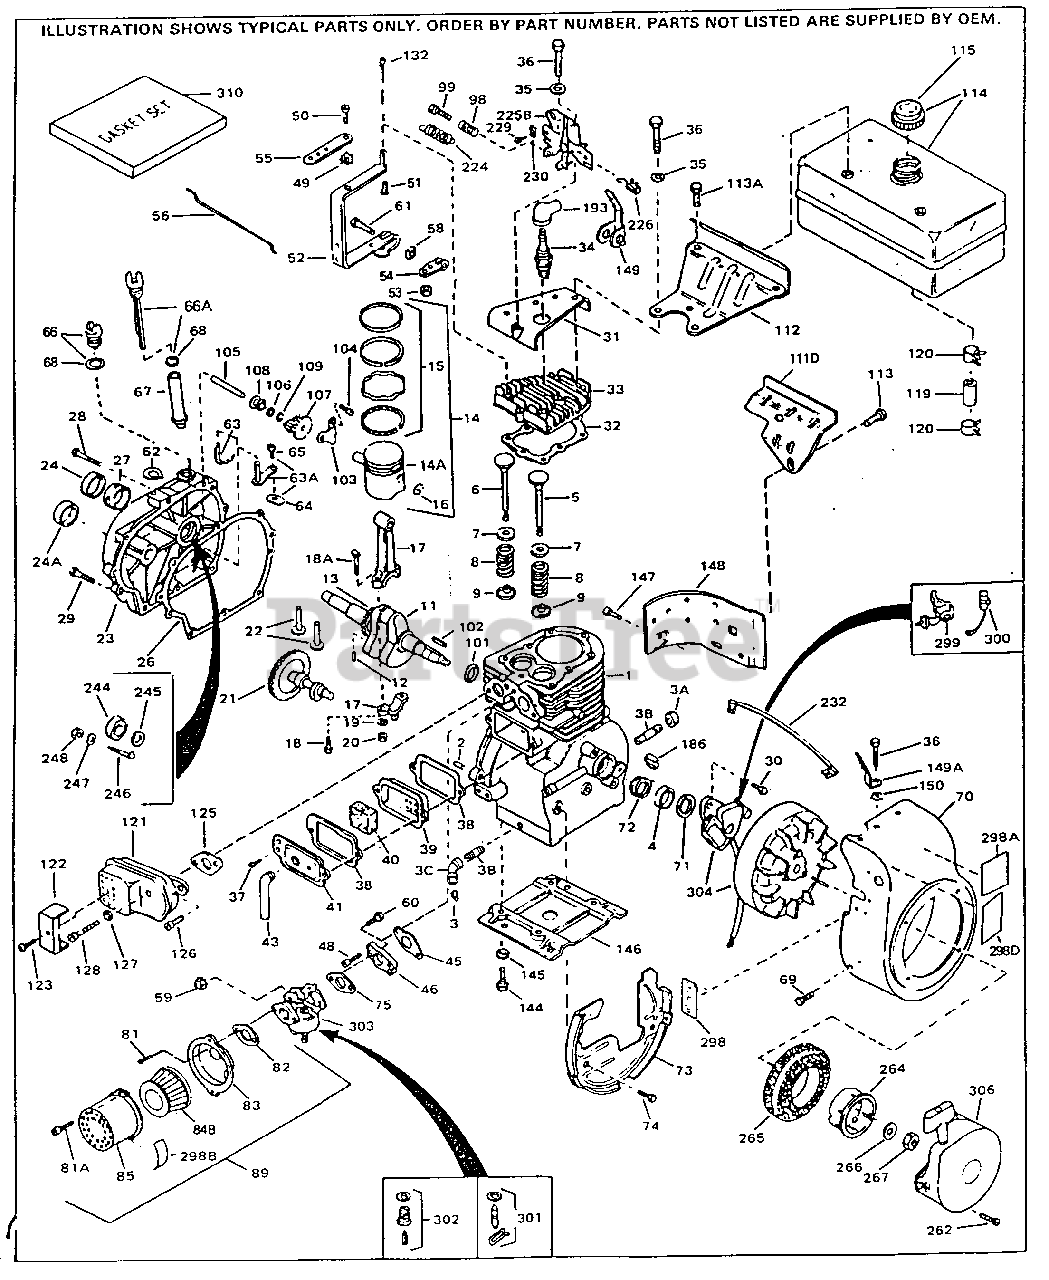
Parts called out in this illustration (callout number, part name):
1	"Cylinder (Incl. 2,3,4,5,184) 2-5/8" B ore
2	Dowel Pin
3	Oil Drain Plug (Sq. hd., 1/4-18)
4	Seal, Oil
5	Intake Valve (Std.) (Incl. 9)
5	Intake Valve (1/32" OS) (Incl. 9)
6	Exhaust Valve (Std.)(Incl. 151)
6	Exhaust Valve (1/32" OS) (Incl. 151)
7	Valve Spring Cap
8	Valve Spring
9	Cap, Lower valve spring
11	Crankshaft (Incl. 12 & 13)
12	Pin, Crankshaft gear Used in early pr oduction. This gear is serviceable O NLY when itis pinned to the crankshaf t.
13	Gear, Crankshaft Used in early produc tion. This gear is serviceable ONLY when itis pinned to the crankshaft.
14	Piston, Pin & Ring Set (Std.) 2-5/8" Bore
14	Piston, Pin & Ring Set (.010" OS)
14	Piston, Pin & Ring Set (.020" OS)
14A	Piston & Pin Ass'y. (Std.)(2-5/8") In cl. 16
14A	Piston & Pin Ass'y. (.010" OS) Incl. 16
14A	Piston & Pin Ass'y. (.020" OS) Incl. 16
15	Ring Set (Std.) (2-5/8" Bore)
15	Ring Set (.010" OS)
15	Ring Set (.020" OS)
16	Piston Pin Retaining Ring
17	Rod Assy., Connecting (Incl. 18)
18	Screw, Connecting rod Late production
18A	Bolt, Connecting rod Early production
19	Washer duction)
20	Connecting rod nut Used on early pro duction
21	Camshaft
22	Lifter, Valve
23	Cover, Cylinder (Incl. 24, 27 & 105)
24	Oil Seal
26	* Gasket, Cylinder cover
27	Bushing, Crankshaft
28	Screw, 1/4-20 x 1-1/4"
29	Screw, 1/4-20 x 1-3/4"
30	Screw, 1/4-20 x 5/8"
31	Cover, Cylinder head
32	* Gasket, Cylinder head
33	Head, Cylinder (Incl. 3 of 36)
34	Resistor Spark Plug - RJ17LM
35	Washer, Flat (Use as required)
36	Screw, 5/16-18 x 2" (Use as required)
36	Screw, 5/16-18 x 2-1/4" Use as requir ed
36	Screw, 5/16-18 x 2-1/2" Use as requir ed
37	Screw, 10-24 x 1/2" (Use as required)
37	Screw, 10-24 x 5/8" (Use as required)
38	* Gasket, Breather cover
39	Breather Body
40	Breather Element
41	Valve Cover
45	* Gasket, Intake
46	Flange, Carburetor (Incl. 79 & 80)
48	Screw, 5/16-18 x 3/4"
49	Lock Washer #8
50	Screw, 8-32 x 5/16"
51	Rivet, Split Used on early production
52	Lever, Governor New lever does not ne ed 1 of Ref #49,51,53,54,132,133
53	Lock Nut, 8-32
54	Governor Lever Clamp
55	Bracket, Adjusting
56	Link, Throttle
58	Lock Nut, 10-32
59	Nut & Lock Washer 1/4-28
60	Screw, 1/4-28 x 1-1/8"
61	Screw, 10-32 x 3/4"
62	Retaining Ring
63	Rod Assy., Governor This one piece go v. rod is no longer used. It is repla ced by 30699C assy., Ref.#63A
63A	Rod Assy., Governor (Incl. 64 & 65)
64	Yoke, Governor
65	Screw, 6-40 x 5/16"
66A	Dipstick (Incl. 68)
67	Oil Fill Tube
68	"O" Ring
69	Screw, T-40, 5/16-24 x 21/32"
70	Blower Hsg. (For elec.starter) Incl. 1 89,190
73	Blower Housing Baffle
74	Screw, 1/4-20 x 5/8"
75	* Gasket, Carburetor
81	Screw, 10-32 x 1/2"
81	Screw, 5/16-18 x 3/4"
81	Screw, 10-32 x 1-1/8" Use as require d
81A	Screw, 8-32 x 3/8"
82	* Gasket, Air cleaner
83	Bracket, Air cleaner
84B	Air Filter (Paper) also available in Packaged Part #740029B
85	Body, Air cleaner
89	Air Cleaner Ass'y. (Incl. 81,81A,82,8 3,84,85,90G & 298B) (Use as required)
98	Compression Spring (Used with 650688 screw) (Use as required)
98	Compression Spring (Used with 29500 s crew)(Use as required)
98	Compression Spring (Used with 650549 screw) (Use as required)
99	Screw, 8-32 x 3/4" (Use as required)
99	Screw, 5-40 x 7/16" (Use as required)
99	Screw, 10-32 x 1 (Use as required)
102	Key, Flywheel
103	Bracket, Governor gear
104	Screw, 10-24 x 1/2"
105	Shaft, Mechanical governor
106	Washer, Flat
107	Gear Assy., Governor (Incl. 106)
108	Spool, Governor
109	Retaining Ring
113	Screw, T-30, 1/4-20 x 1/2"
115	Fuel Cap (Red 1-1/2" ID) (also availa ble in Packaged Part #740005B) (Spur t Resistant, Low Profile) (Use as req uired)
115	Fuel Cap (Red Plastic) (Spurt Resista nt, High Profile) (Use as required)
115	Fuel Cap (White Plastic)(Standard) As req.
119	Fuel Line (8.62") uired)
119	Fuel Line (Braided 16") Use as requir ed
119	Fuel Line (Braided 32") Use as requir ed
120	Fuel Line Clamp
121E	Muffler (Incl. 124, 124A & 124B) (Thi s spark arrester mufflercan be used o n any model)
125	* Gasket, Exhaust
132	Screw, 8-32 x 1/2" (Early production)
132	Screw, 8-32 x 5/16" Early production
144	Screw, 5/16-18 x 3/4"
146	Base, Engine mounting
147	Screw, 10-24 x 1/2"
148	Extension, Blower housing
186	Wire Clip
226	Terminal Assy.
229	Screw, 10-32 x 3/8"
230	Conduit Clip
232	Ground Wire
262	Screw, 1/4-28 x 7/16"
264	Cup, Starter
265	Screen, Starter cup
266	Washer, Belleville
267	Nut, Hex
298	Decal, Instruction
298A	Decal, H.P. (5 H.P.) Use as required
298A	Decal, H.P. (6 H.P.) Use as required
298A	Decal, 5 HP Mini-Bike Use as require d
298A	Decal, Name
298B	Decal, Air cleaner
299	Breaker Points (also available in Pac kaged Part #740037B)
300	Condenser (also available in Packaged Part #740037B)
301	Inlet Needle, Seat & Clip Assy.
303	Carburetor (Incl. 75 & 301) (Refer to Division 5, Section A, page 206for b reakdown)
304	Magneto NOTE: The complete magneto i s not available as an assembly. The magneto number is shown for reference purposes only. Order component part s individually, as shown in parts lis t. (Refer to Division 5, Section B, p age 24 for breakdown)
306	Rewind Starter Refer to Division 5, S ection C, page 25 for breakdown
310	* Gasket Set (Incl. items marked *)
